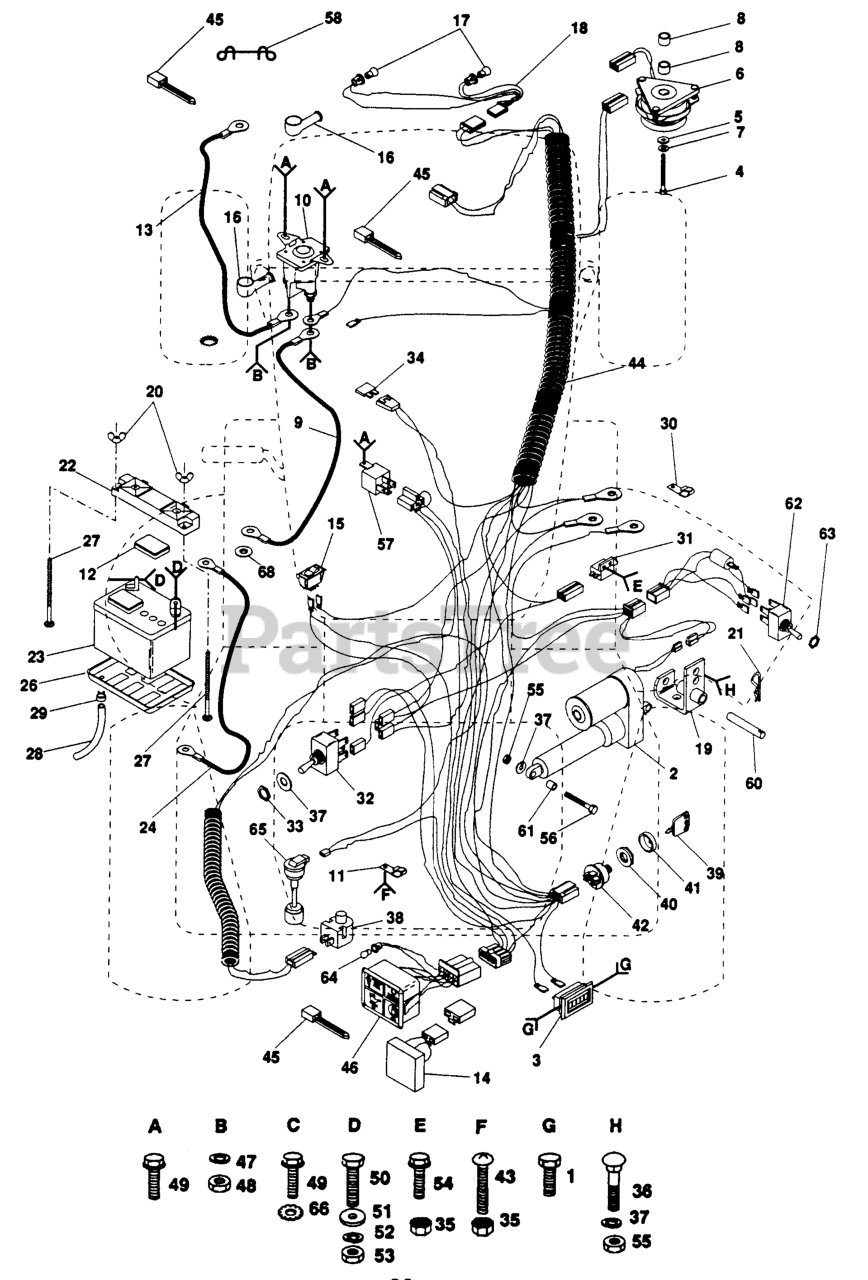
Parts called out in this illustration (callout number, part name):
1	Screw #10-24 x 1/2
2	ELECT ACTUATOR
3	HOUR METER T
4	Bolt, Hex 7/16-20 x 1-1/2 Gr. 8
6	ELECTRIC CLUTCH T
7	LOCKWASHER
8	SPACER-CLUTCH GT
9	CABLE-BATTERY YTV
10	SOLENOID
11	CLIP T
12	CAP BATTERY NLA
13	CABLE, STARTER
14	SENSOR LOW VOLTAGE
16	TERMINAL COVER
17	BULB-LIGHT T
18	HARNESS, LIGHT SOCKET
20	WING NUT
22	TERMINAL GRD YTV
23	BATTERY
24	CABLE T
26	BATTERY TRAY T
28	PLASTIC TUBE
29	HOSE CLAMP T
31	SWITCH-INTER. GT
32	SWITCH,PTO
33	HEX NUT T
35	Nut, Keps #10-32
36	BOLT D
37	WASHER, LOCK 3/8
38	RP.SWITCH.PLUNGER.NC.GRAY
39	KEY.MOLDED.GENERIC
40	NUT IGNITION
41	COVER KEY IGNITIO
42	SWITCH
44	HARNESS, IGNITION
45	TIE GUIDE
46	LIGHT PACKAGE
47	LOCKWASHER
48	NUT
49	SCREW ST
50	BOLT.HEX.1/4.X.3/4.DICHROMATE
51	WASHER
52	LOCKWASHER
53	NUT
54	SCREW **
55	NUT.HEX.3/8-16UNC
56	BOLT-HEX EAK
57	RELAY.ASSY.T
60	PIN-ACTUATOR T
62	LIFT,SW WIRING
63	LOCKWASHER
64	BULB LIGHT T
65	SENSOR, LOW FUEL
66	LOCKWASHER
67	WASHER
68	Washer, Lock, Int. tooth 1/4
